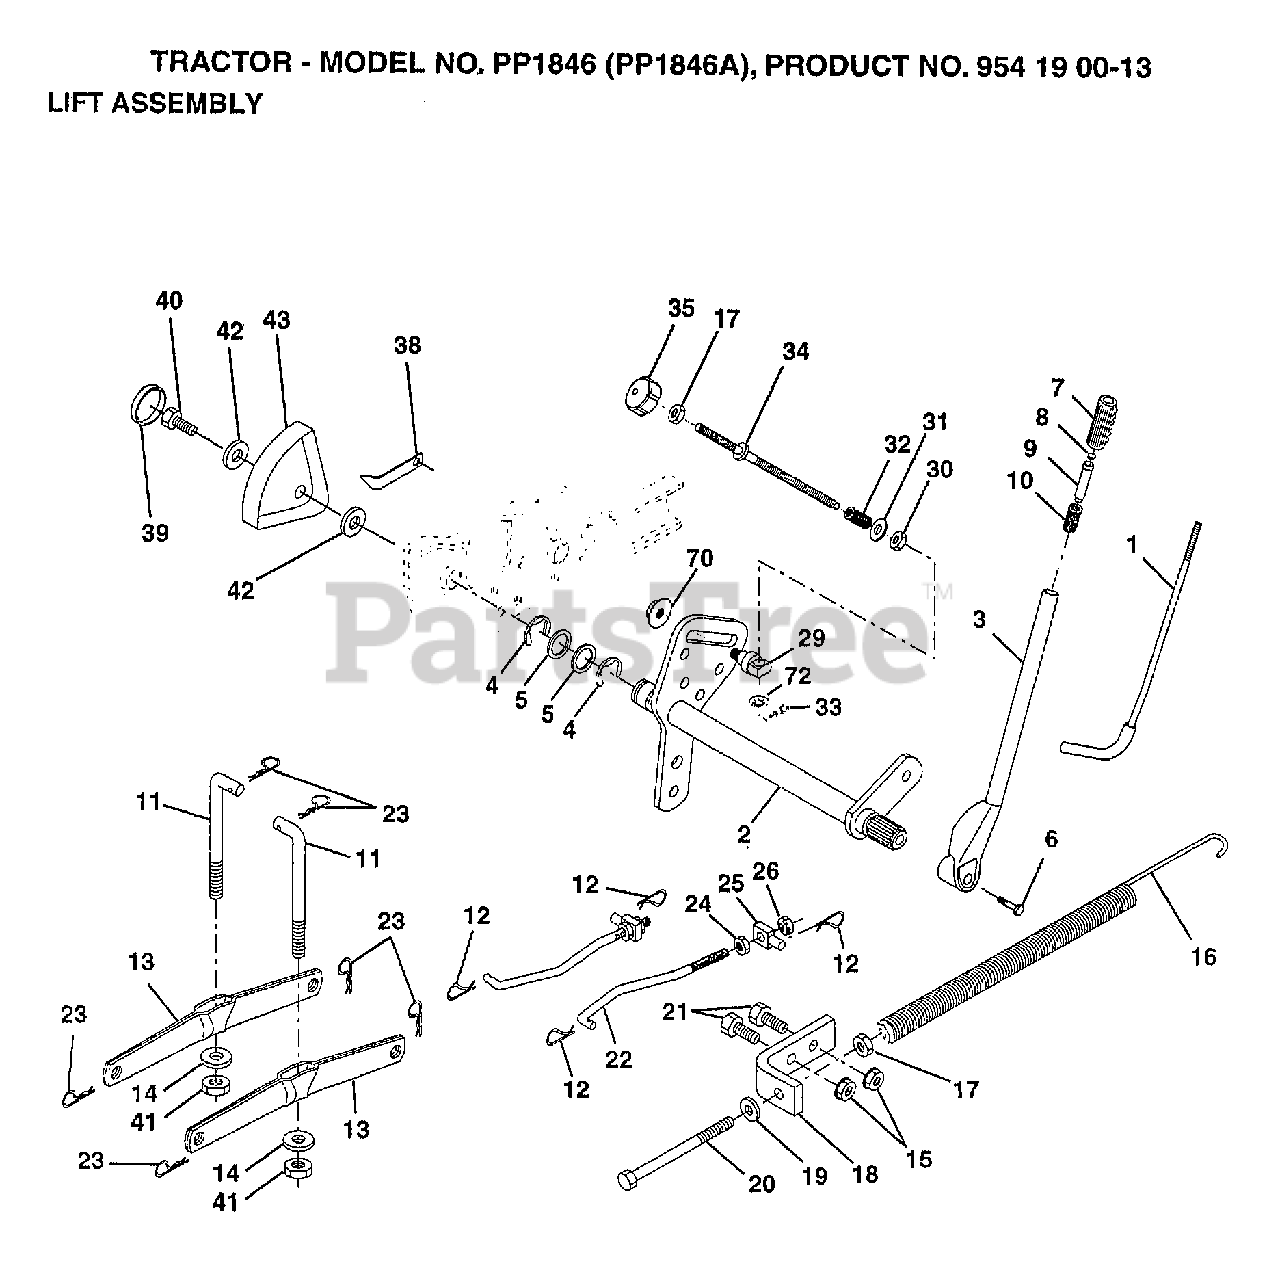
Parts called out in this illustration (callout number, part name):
1	LEVER ROD LT
2	SHAFT AMS LIFT
4	E-RING
5	WASHER
6	"BOLT,HEX"
7	GRIP
10	SPRING T
11	LINK.LIFT.MWR.VGT
12	RETAINER.SPRING
13	ARM SUSP REAR
14	BEARING PVT LH
17	NUT
18	BRACKET SPRING AS
19	WASHER
20	BOLT-ADJ SPRING T
21	BOLT
22	LINK.FRONT
24	NUT
25	TRUNION
26	NUT.LK.W/WSH.1/2.
29	TRUNNION
30	NUT T
31	WASHER
32	SPRING.COMP.INF.H
34	ROD.ADJ.LIFT
35	KNOB INF 3/8-16
36	SCREW
38	POINTER-INDICAT
39	"PLUG,HOLE"
40	SCREW
41	NUT.CROWNLOCK.3/8
42	WASHER
43	HEIGHT INDICATOR
70	NUT.HXFLG.LOCK.
72	NUT PUSH M
